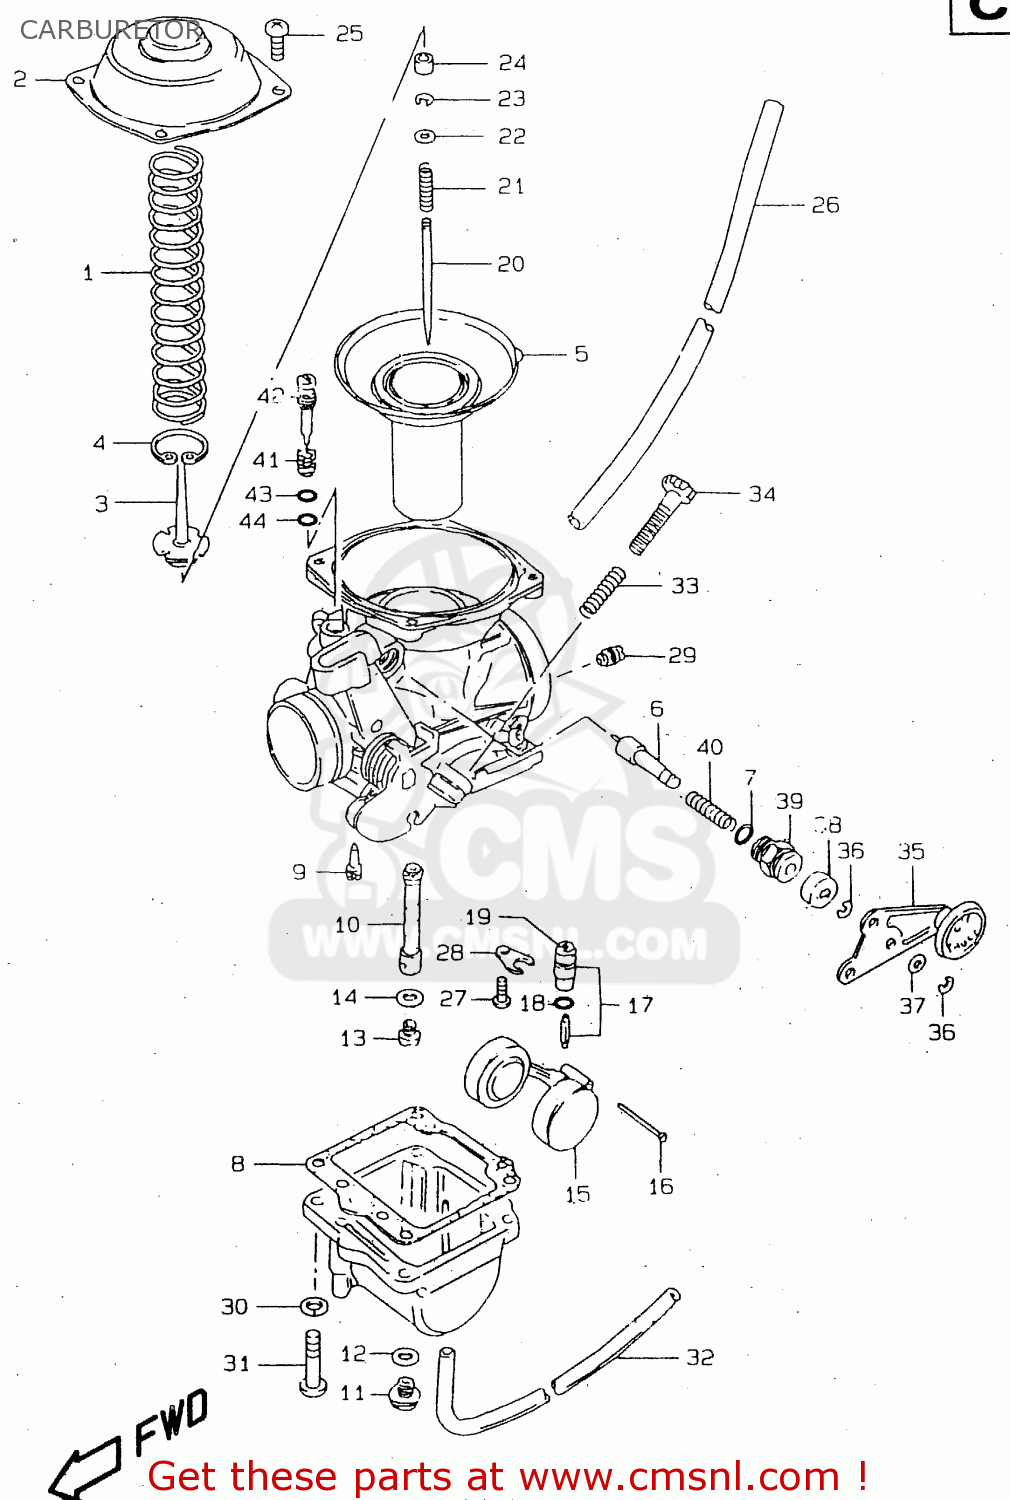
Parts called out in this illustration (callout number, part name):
1	SPRING
2	COVER
3	HOLDER,GUIDE
4	E RING
5	DIAPHRAGM ASSY
6	PLUNGER ASSY
7	O RING
8	GASKET,FLOAT CAHMBER (NAS)
9	JET,PILOT(42.5)
10	JET,NEEDLE(P-1)
11	PLUG,DRAIN
12	GASKET (NAS)
13	JET,MAIN(130)
14	WASHER
15	FLOAT
16	PIN,FLOAT
17	VALVE ASSY,NEEDLE
18	O-RING,NEEDLE VALVE
19	FILTER
20	NEEDLE,JET
21	SPRING
22	WASHER
23	CLIP
24	RING
25	SCREW
26	HOSE(5X8.2X600)
27	SCREW 4X6
28	PLATE
29	JET,AIR(150)
30	LOCK,WASHER
31	SCREW
32	HOSE(3.5X6.5X600)
33	SPRING,THROTTLE SCREW
34	ADJUSTER
35	STARTER LEVER ASSY
36	E RING
37	WASHER
38	CAP,STARTER VALVE
39	GUIDE SCREW,PLUNGER
40	SPRING
41	SPRING
42	SCREW,PILOT AIR
43	WASHER
44	O RING,PILOT AIR SCREW
